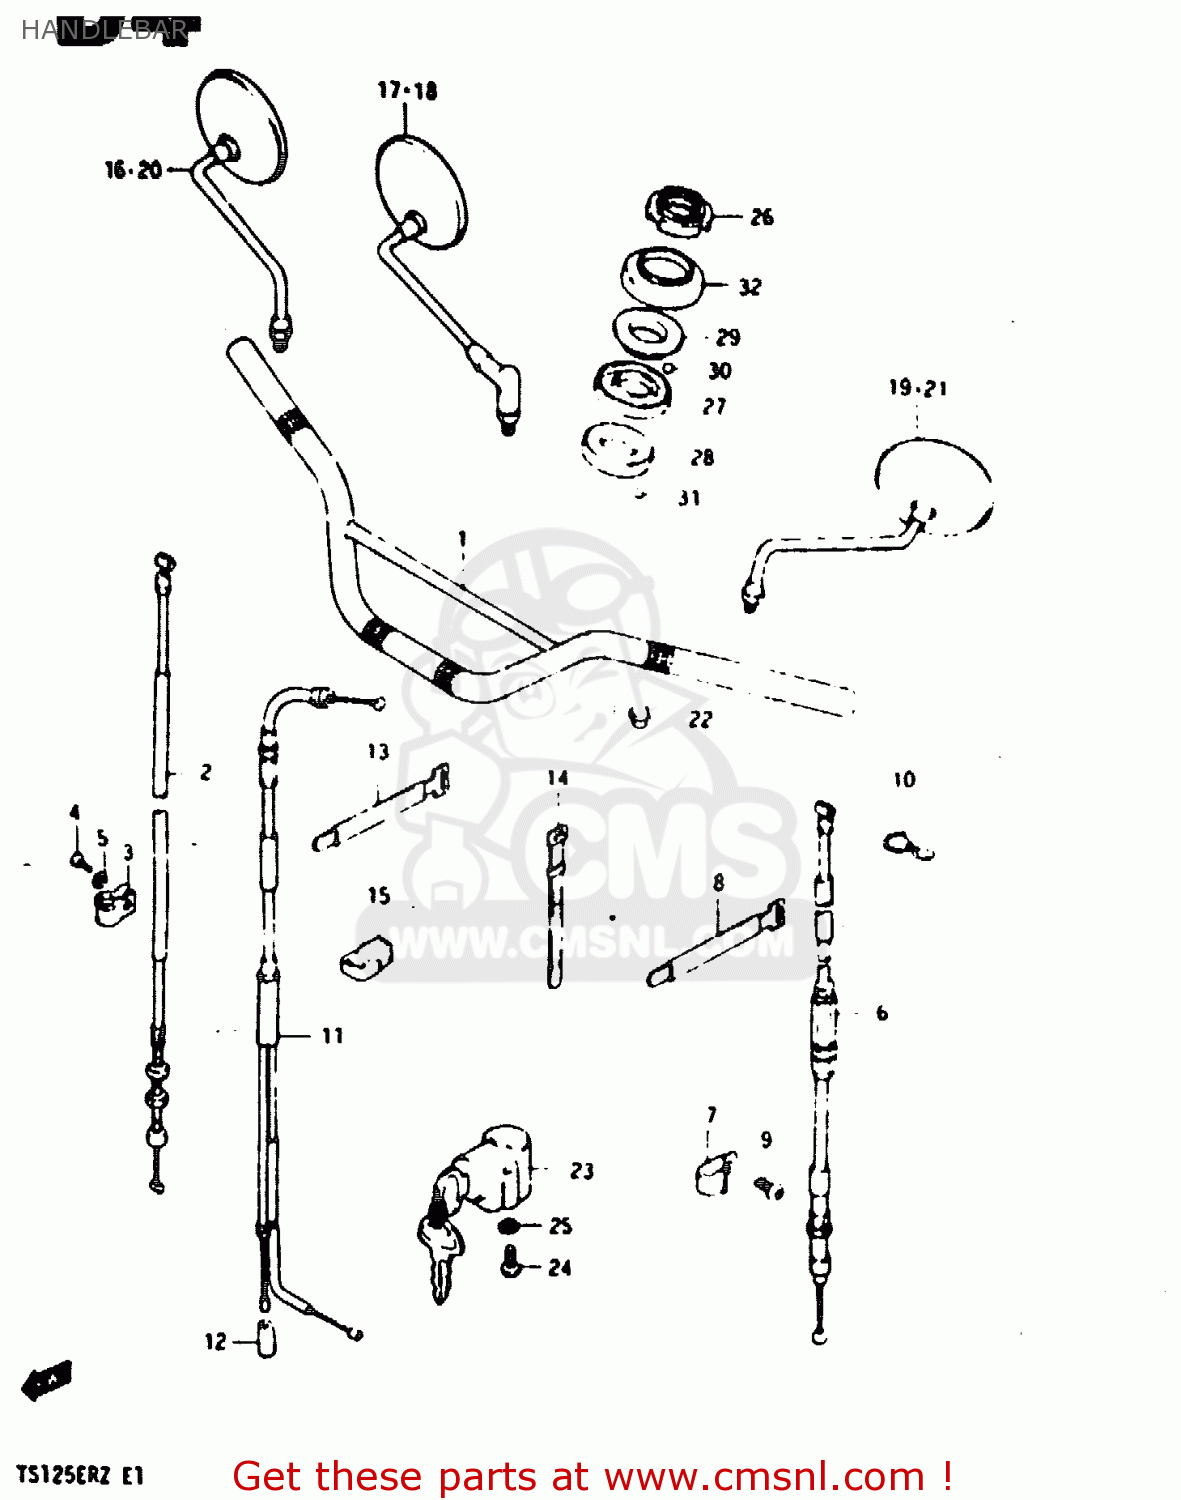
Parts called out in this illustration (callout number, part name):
1	HANDLEBAR, BLACK
2	CABLE, FRONT BRAKE
3	CLAMP,FR BRAKE CABLE
4	SCREW
5	LOCK WASHER
6	CABLE,CLUTCH
7	CLAMP
8	CLAMP
9	SCREW
10	CLIP
11	CABLE ASSY, THROTTLE
12	SEAL,DUST(7X18X30)
13	CLAMP(L:120)
14	CLAMP
15	GUIDE
17	MIRROR ASSY, REAR VIEW
22	CAP
23	LOCK ASSY,STEERING
24	SCREW
25	LOCK WASHER
26	NUT,STEERING STEM(25X44X10)
27	RACE,STEERING INNER UPR
28	LACE,STEERING INNER LWR
29	RACE,STEERING OUTER UPR
30	BALL
31	BALL
32	DUST SEAL,STEERING UPR
